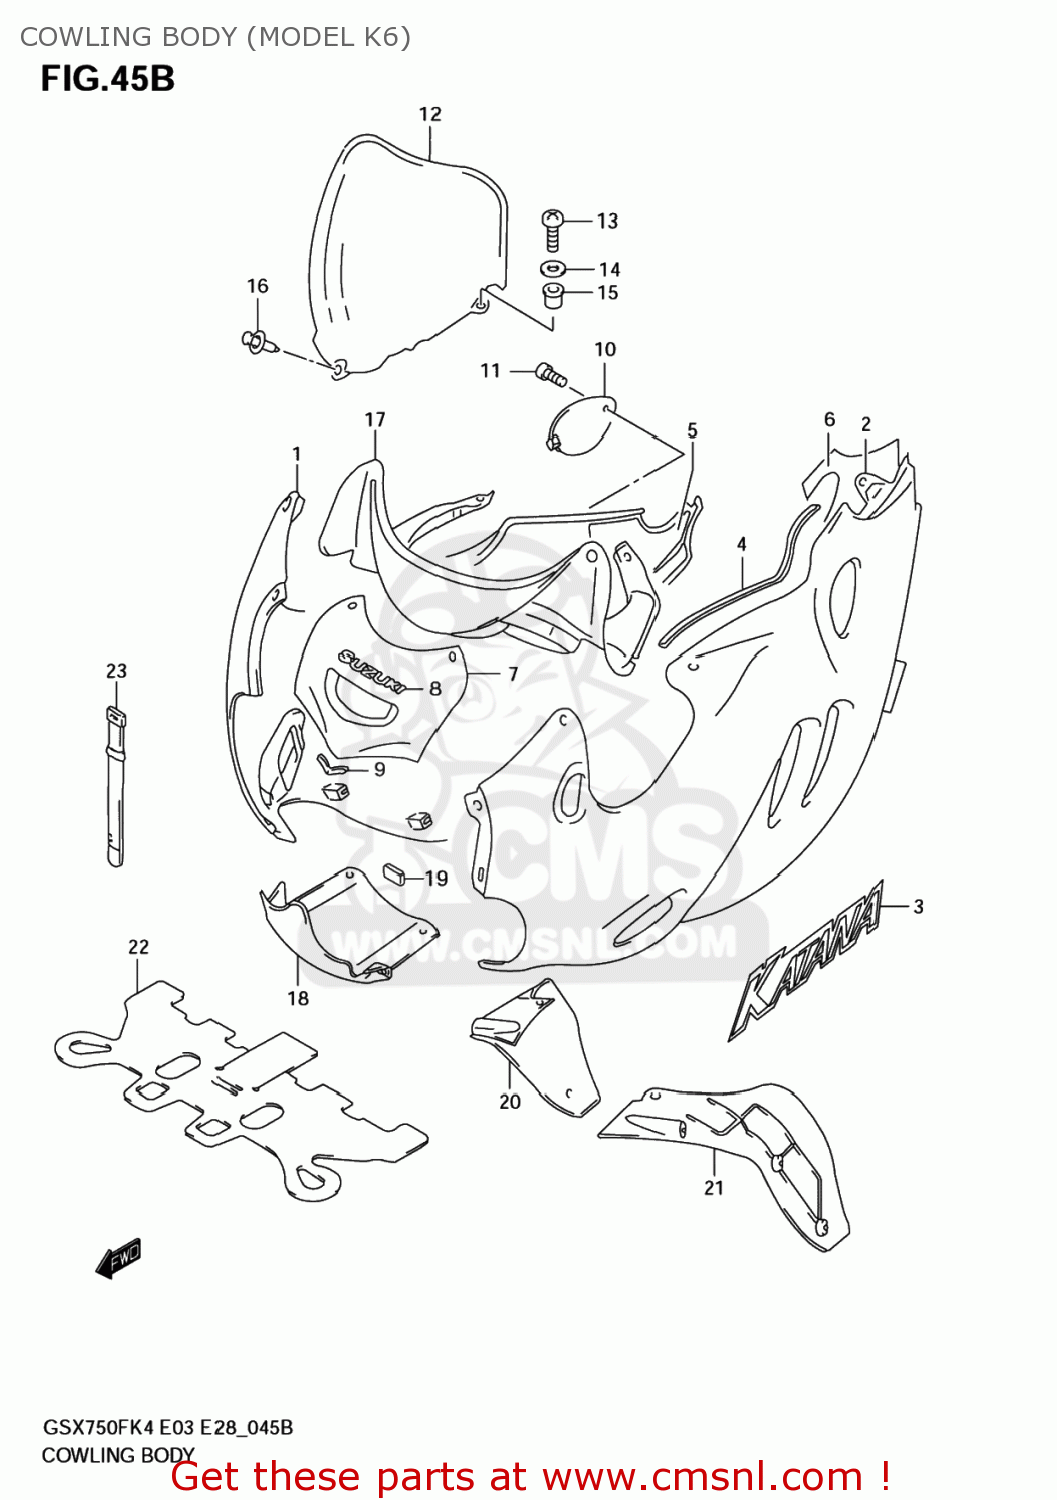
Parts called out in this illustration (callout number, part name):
1	COWLING ASSY,SIDE,R
2	COWLING ASSY,SIDE,L
3	EMBLEM,KATANA
4	MOLD,COWLING
5	SHIELD,COWLING COVER,R
6	SHIELD,COWLING COVER,L
7	PANEL,COWLING CTR UPR
8	EMBLEM,SUZUKI
9	CUSHION,CTR PANEL UPR
10	LID,OIL
11	SCREW(6X16)
12	WINDSCREEN
13	SCREW(5X14)
14	WASHER
15	NUT
16	CLIP(BLACK)
17	PANEL,METER
18	PANEL,COWLING CTR LWR
19	CUSHION,CENTER PANEL,LOWER
20	PANEL,COWLING INNER,R
21	PANEL,COWLING INNER,L
22	PLATE,AIR GUIDE
23	CLAMP(L:165)
